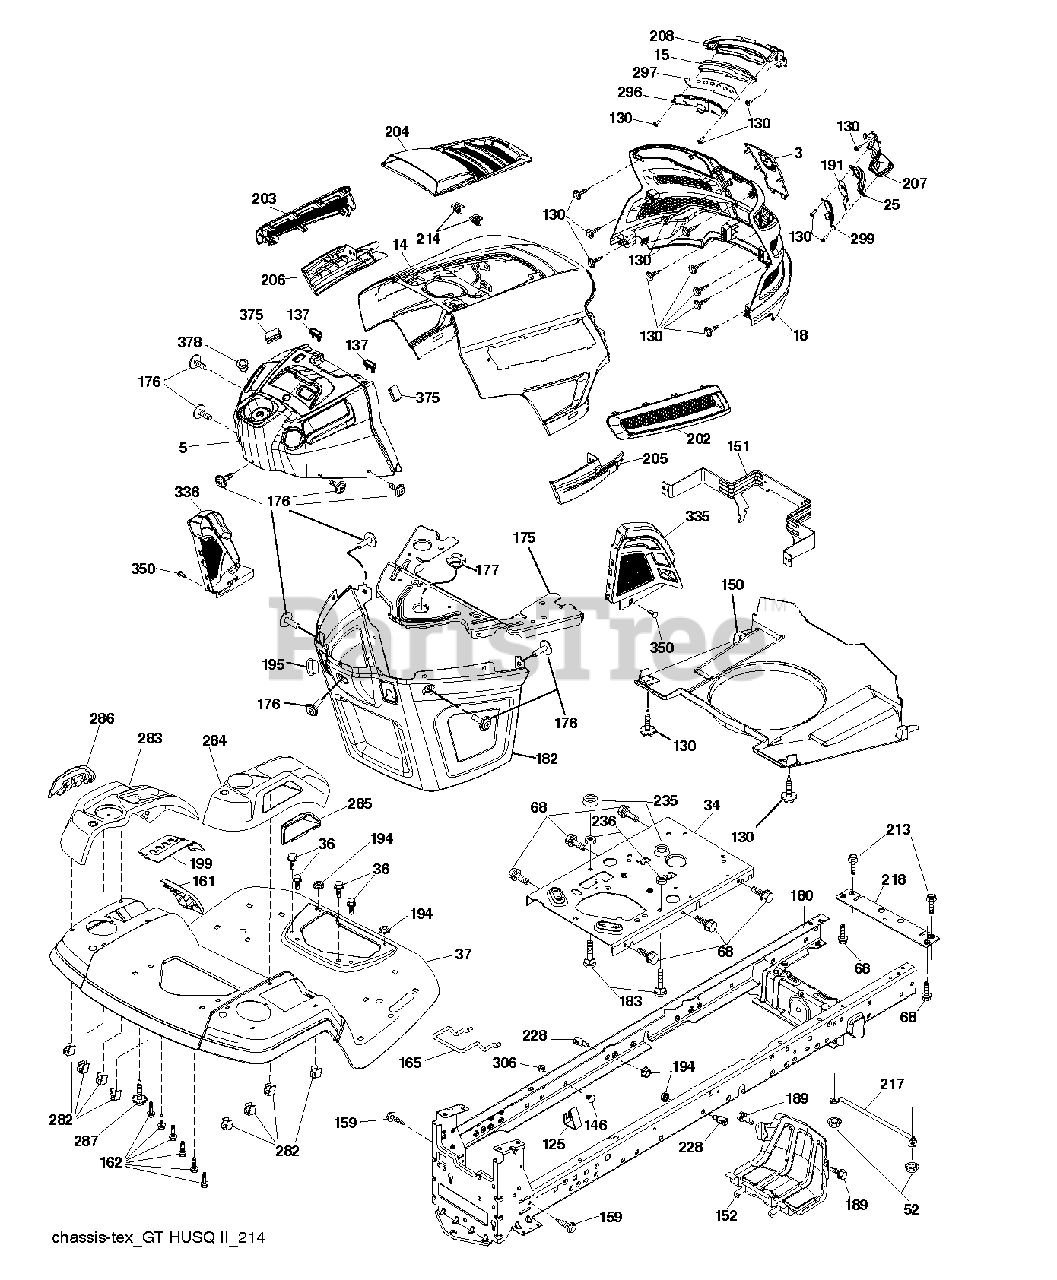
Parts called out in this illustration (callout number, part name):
3	APPLIQUE.SUBASM.GT.HUSQ.II
5	DASHBOARD TEX;GT2;UPPER S_M_
14	HOOD.ASM.HUSQVARNA.GT.TEX.ORAN
15	LED LIGHT.LH
18	GRILLE SUBASM.GT.II.LOW.HDLGHT
25	LENS.RH
34	PLATE.ENGINE.WELDED.CHASSIS
36	SCREW 5/16"
37	FENDER.TLT.FS.W/CPH/FW/RSF.668
52	LOCKNUT
68	SCR 5/16-18 X 1/2 SELFTAP ZN
125	CLIP.FUEL.LINE
130	SCREW.#10 X 0.750.BOS
137	BUMPER DASH
146	BOLT.RDHD.SHT.SQNK.3/8-16X5/8
150	AIR.DUCT.GTV.BLACK
151	BRACKET.PIVOT.HOOD.GT.HUSQ.II
152	SHIELD.BROWNING.PNT.GT.V2
159	SCREW, 3/8-16X3/4
161	WINDOW.FUEL.LT.HUSQ.TEX.498
162	SCREW.HI-LO.CONSOLE
165	SUPPORT.TANK.REAR.W/TEX
175	Crossmember Plate
176	SCREW.#10-24X5/8.RN.QU
177	BUSHING STEERING
180	CHASSIS
182	DASH.LOWER.COMMON.12V.ADAPTOR
183	BOLT.5/16-18X1-1/4 FULL THD
189	SCREW
191	INSERT INFLECT.RH
194	NUT LOCK HEX FLANGE 5/16-18
195	PLUG.HOLE.DASH.LOWER.12V.BLK
199	PLATE.DECK.LIFT.HUSQ.LT
202	VENT.SIDE.RH.GT.HUSQ.II.
203	VENT.SIDE.LH.GT.HUSQ.II.498
204	VENT.TOP.HUSQ.GT2
205	SIDE.TRIM.RH.GT.HUSQ.II
206	SIDE.TRIM.LH.GT.HUSQ.II.GRAY
207	BEZEL GT2 LED RH W/ LOWER.ATT
208	BEZEL GT2 LED LH W/ LOWER ATT
213	BOLT
214	CLIP.RETAINER.TINNER.
217	ROD.PIVOT.HOOD
218	X-PIECE.HOOD.STOP.NON/
228	STUD.FASTNER.W/ANTI-ROTATE
235	SPACER FENDER
236	NUT.CENTERLOCK.5/16-
282	CLIP.RETAINER.CONSOLE.LT.HUSQ
283	CONSOLE.DECK.LIFT.R.SDFL.HUSQ
284	CONCOLE.CNTRL.PDL.HUSQ.LT.498
285	CONSOLE INSERT RH
286	CONSOLE.INSRT.LH.HUSQ.LT.BLACK
287	SCREW 1/4X20
296	LED LIGHT.LH
297	INSERT REFECT LH
299	LED LIGHT.RH
306	NUT LOCK FLG 3/8-16 UNC
335	COVER.LOWER.DASH.RH.BLACK
336	COVER-LH.LOWER.DASH.GT2.BLACK
350	CLIP.X-MAS.TREE
375	BUMPER CLIP-ON. DASH 1"
378	BUSHING FLANGE; PLASTIC
